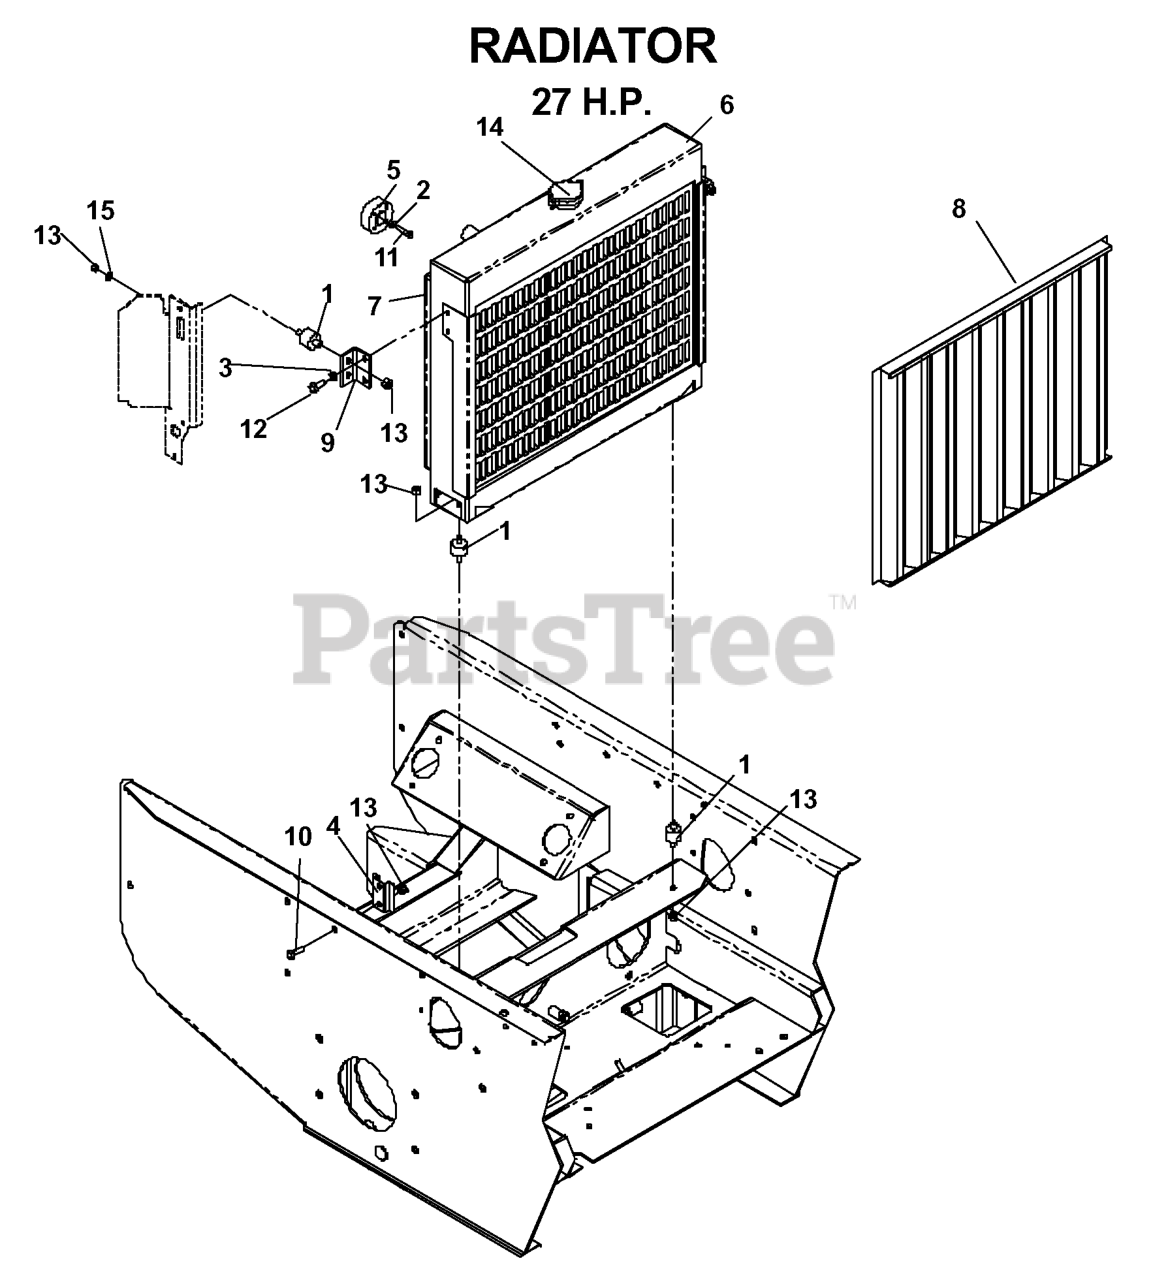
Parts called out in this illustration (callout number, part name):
2	LOCKWASHER 1/4"
3	WASHER.LOCK.HVY.HLCL.SPR.5/16
4	MOUNTING BRACKET
5	FAN SPACER
8	DEBRIS GUARD
9	BRACKET ISO
10	HCS 5/16C X 1
11	BOLT - M6-1.0 X 30MM GR 8
12	HCS 5/16C X 3/4
13	NUT 5/16 NYLOC
14	RADIATOR CAP
15	FLAT WASHER 5/16 SAE
539106326	LOWER HOSE
539106402	OVERFLOW TANK ASM
